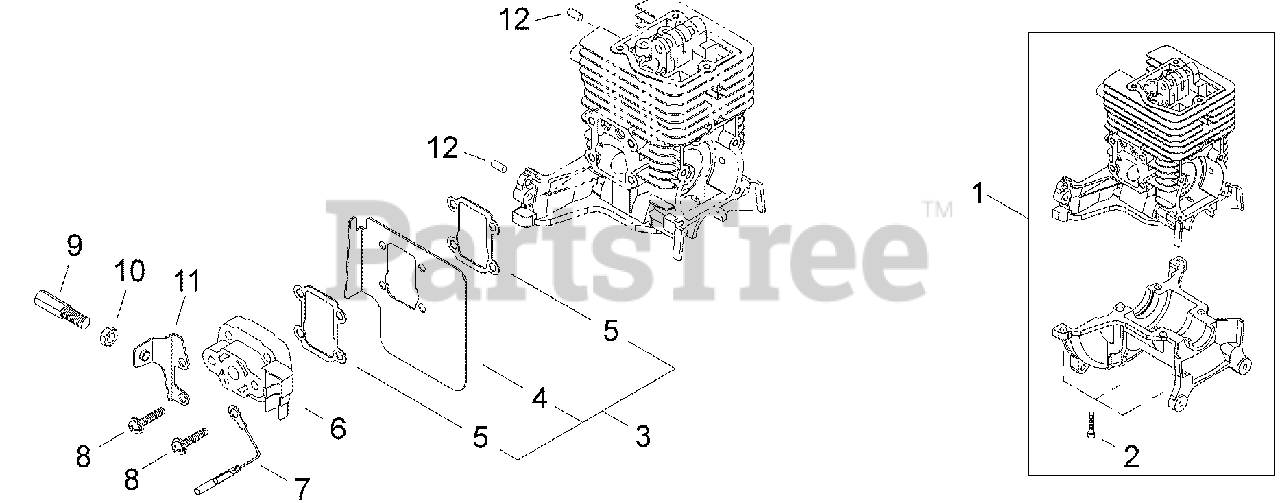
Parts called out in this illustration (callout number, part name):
1	CYLINDER BLOCK SET
2	SCREW - 5X16
3	HEAT DEFLECTOR ASSY
4	DEFLECTOR, HEAT
5	SHIELD, INTAKE
6	INSULATOR
7	LEAD - GROUND
8	SCREW - 5X22
9	NUT, CABLE ADJUST
10	LOCKNUT - 6
11	BRACKET, THROTTLE CABLE
12	PIN - LOCATING
